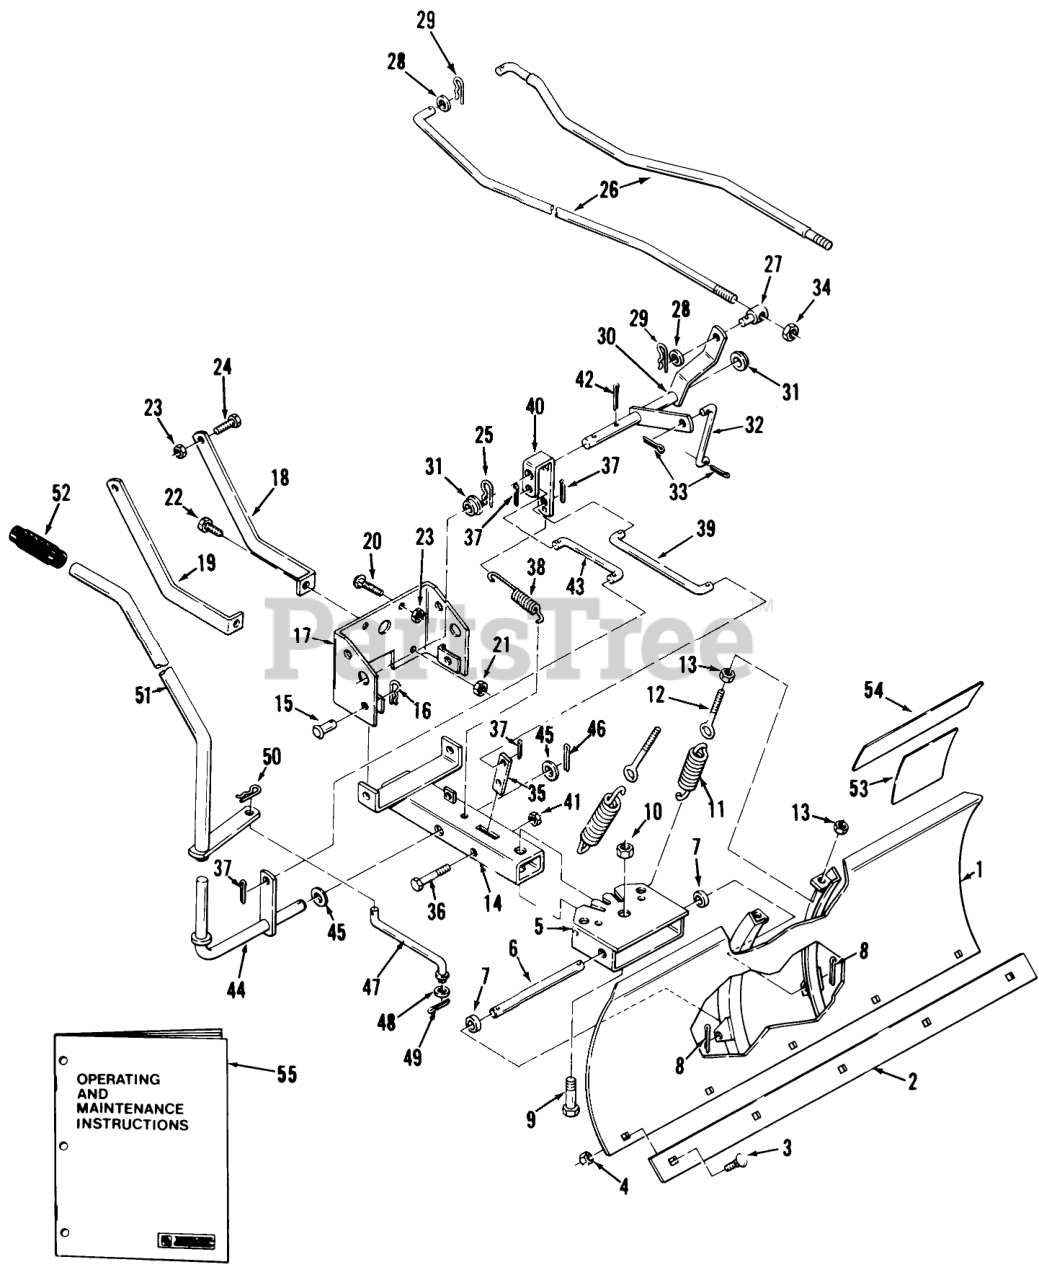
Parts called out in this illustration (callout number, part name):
1	Blade
2	Plate
3	Bolt-Carriage
4	NUT
5	ASSY-QUADRANT R
6	ROD-LOWER
7	Spacer
9	HEX HD CAP SCREW
10	Nut
11	SPRING
12	EYEBOLT
13	Nut
14	Frame
15	CLEVIS PIN
16	Hairpin Cotter
17	Front Support
18	BRACE-FRAME MT LH R
19	BRACE-FRAME MT RH R
20	Bolt-Carriage
21	Nut
22	BOLT
23	Nut
24	Bolt
25	Hairpin
26	ROD LIFT
27	TRUNION
28	Washer
29	Hairpin Cotter
30	Bellcrank Lift
31	BUSHING
32	Rod
33	Pop Rivet
34	Nut
35	LATCH-QUADRANT R
36	HHCS
37	Pop Rivet
38	SPRING
39	ROD-LATCH
40	Bellcrank
41	NUT
42	Cotter Pin
43	ROD-BELLCRANK
44	Handle Pivot
45	Washer
46	Cotter Pin
47	ROD-ANGLING
48	Washer
49	Pop Rivet
50	Hairpin Cotter
51	ASSY-HANDLE R
52	HANDGRIP
53	DECAL-WARNING
55	Operating and Maintenance Instructions (06-42BB01)
55	Operating and Maintenance Instructions (06-42BB02)
